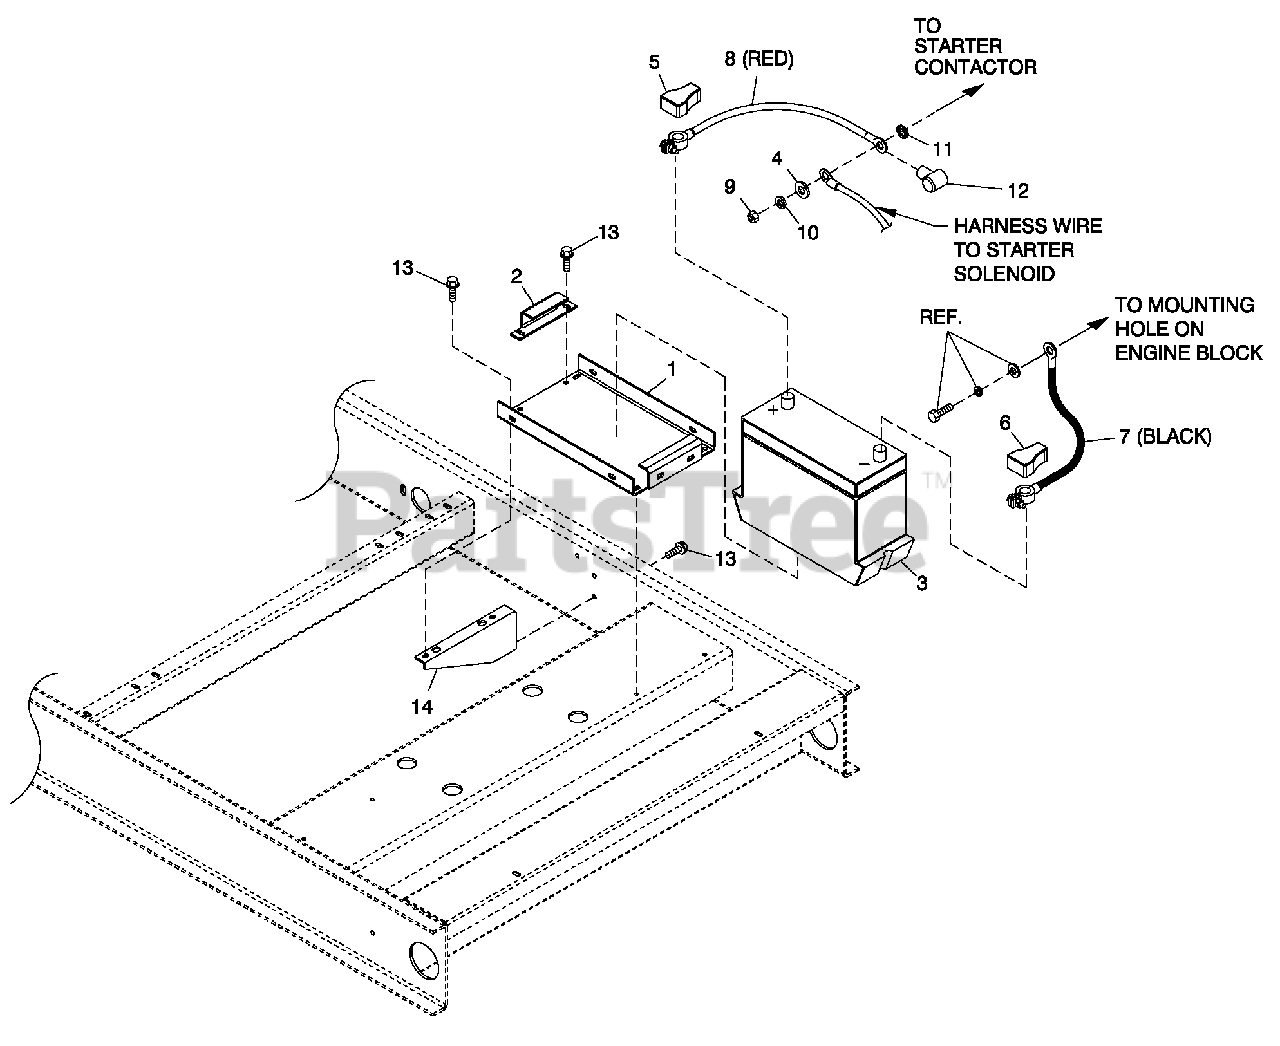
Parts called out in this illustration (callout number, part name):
1	TRAY BATTERY
2	STRAP BATTERY RETAINMENT
3	BATT 12VDC 24F 625
4	WASHER FLAT 3/8-M10 ZINC
5	BATT POST COVER RED +
6	BATT POST COVER BLK -
7	CABLE BATT BLK #1 X 40.00
8	CABLE BATT RED #1 X 35.00
9	NUT HEX M8-1.25 G8 YEL CHR
10	WASHER LOCK M8-5/16
11	WASHER SHAKEPROOF EXT 5/16 STL
12	BOOT BATTERY CABLE
13	SCREW THF M6-1X16 N WA Z/JS
14	SUPPORT BATTERY TRAY
